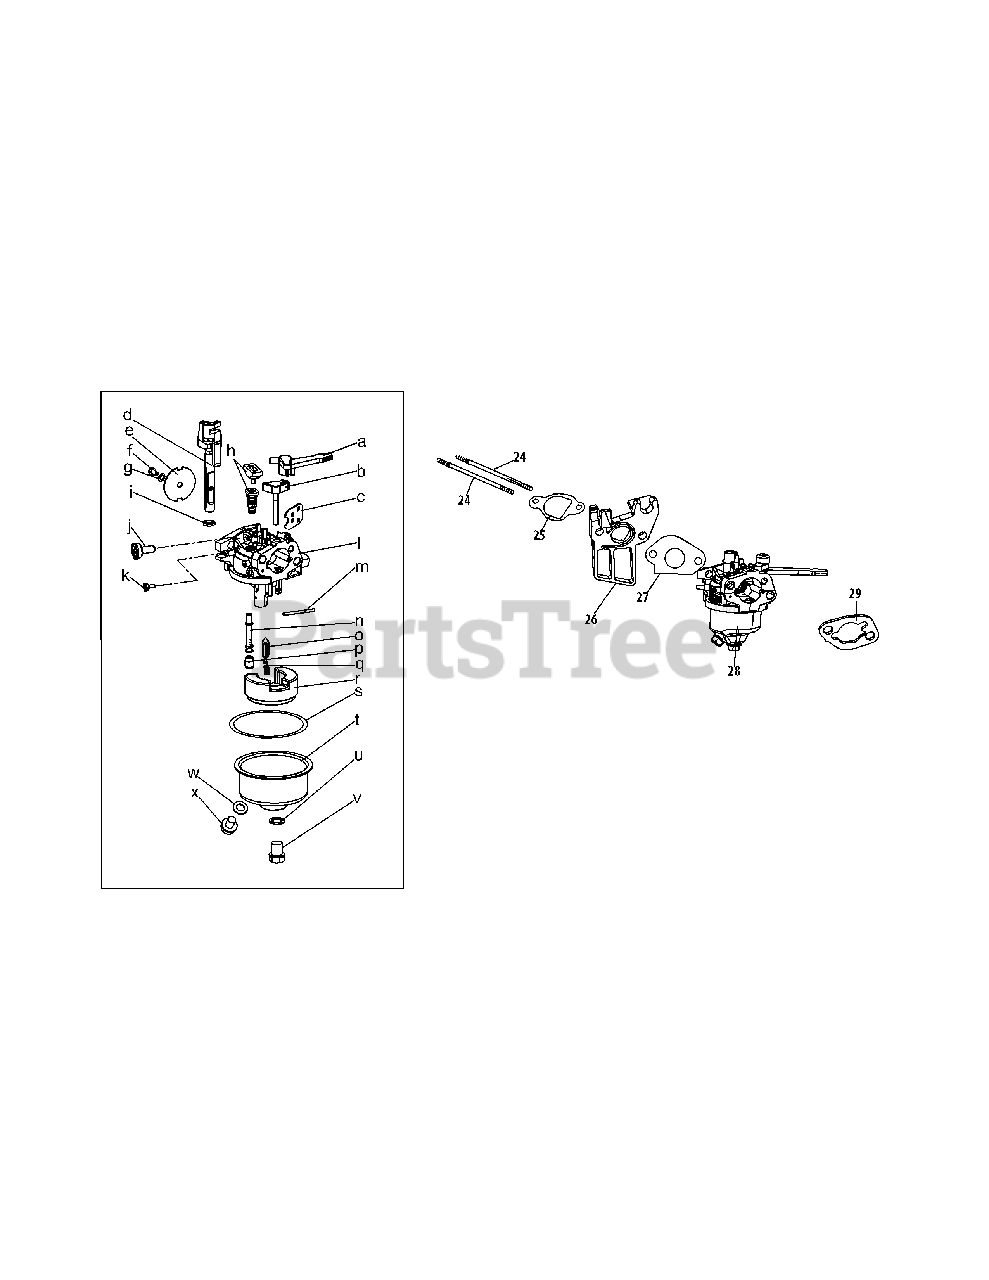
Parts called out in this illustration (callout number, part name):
24	Stud M6×110
25	Carburetor Insulator Gasket
26	Carburetor Insulator
27	Carburetor Gasket
28	Carburetor Assembly
29	Carburetor Gasket Plate
